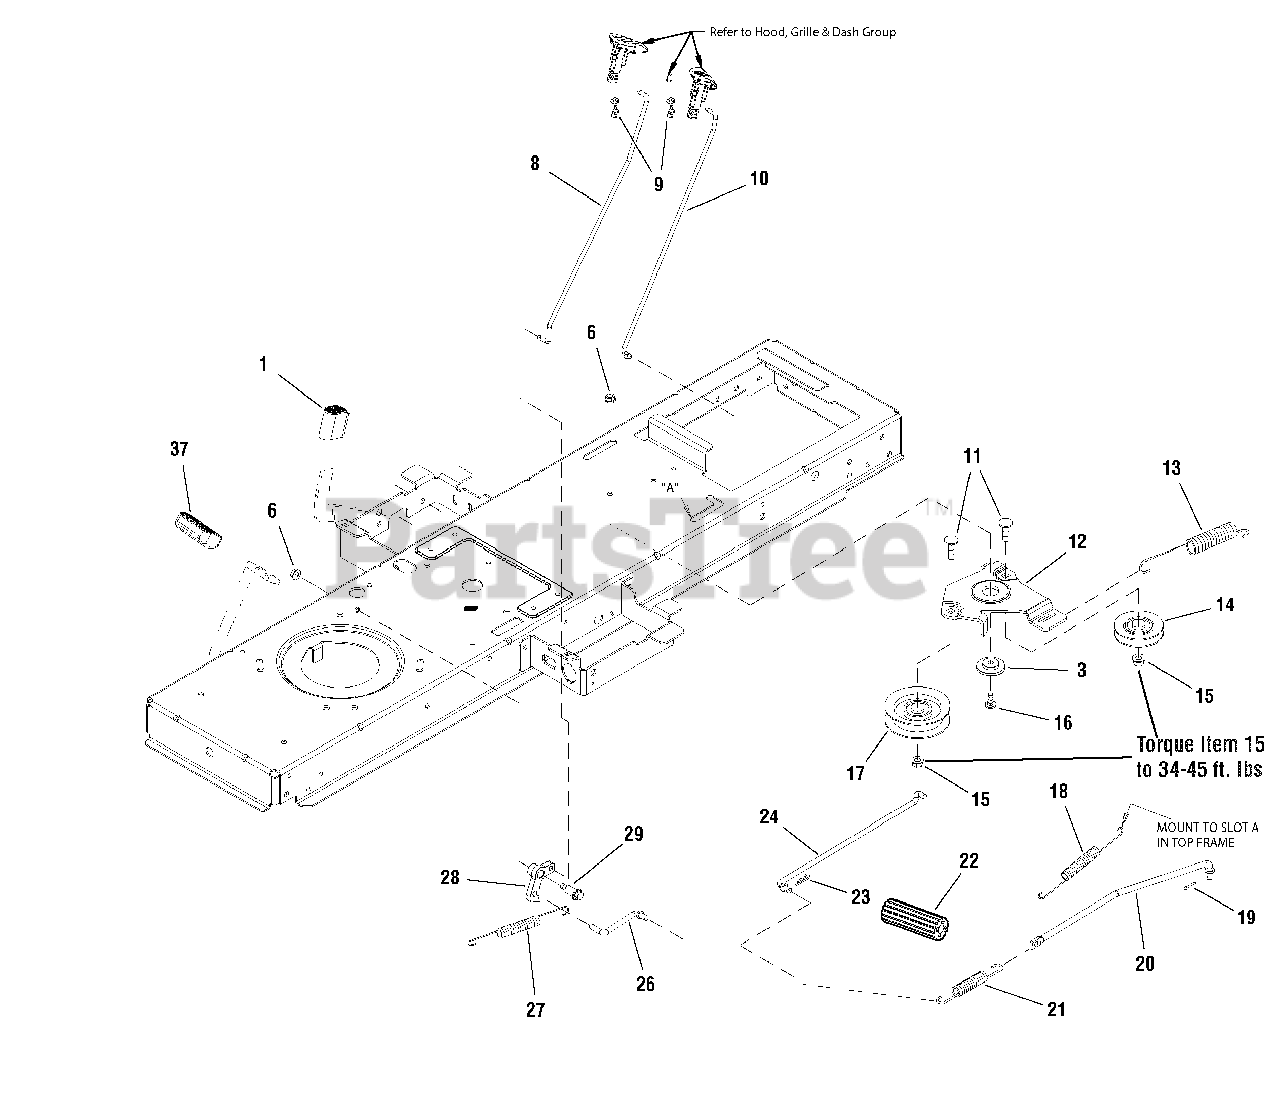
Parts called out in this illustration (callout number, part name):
1	PAD, Foot Pedal Reverse
3	SPACER, Pivot 0.330ID 1.76OD .37TH
6	NUT, Hex, Flange Whizlock, 5/16-18
8	ROD, Cruise Latch, 16.97LG
9	CLIP, Linkage, Black
10	ROD, Parking Brake, 16.38 LG
11	BOLT, Carriage, 3/8-16 x 1-1/2
12	BRACKET, Idler
13	SPRING, Extension 07.52
14	PULLEY, 3 OD Plastic
15	NUT, Hex Flange, ESNA, 3/8-16
16	BOLT, Carriage, 5/16-18 x 1
17	PULLEY, Idler
18	SPRING, Extension
19	PIN, Cotter 3/32 x 3/4
20	ROD, Brake, 15.1"
21	SPRING, Extension 5-3/8"
22	PEDAL, Brake Rubber
23	PIN, Quick
24	ROD, Brake Return, 12.60 LG
26	ROD, Cruise Latch, 2.83 LG
27	SPRING, Tension, Clutch
28	LATCH, Cruise
29	BOLT, Shoulder, 5/16-18 G5
37	PAD, Foot Pedal Forward
